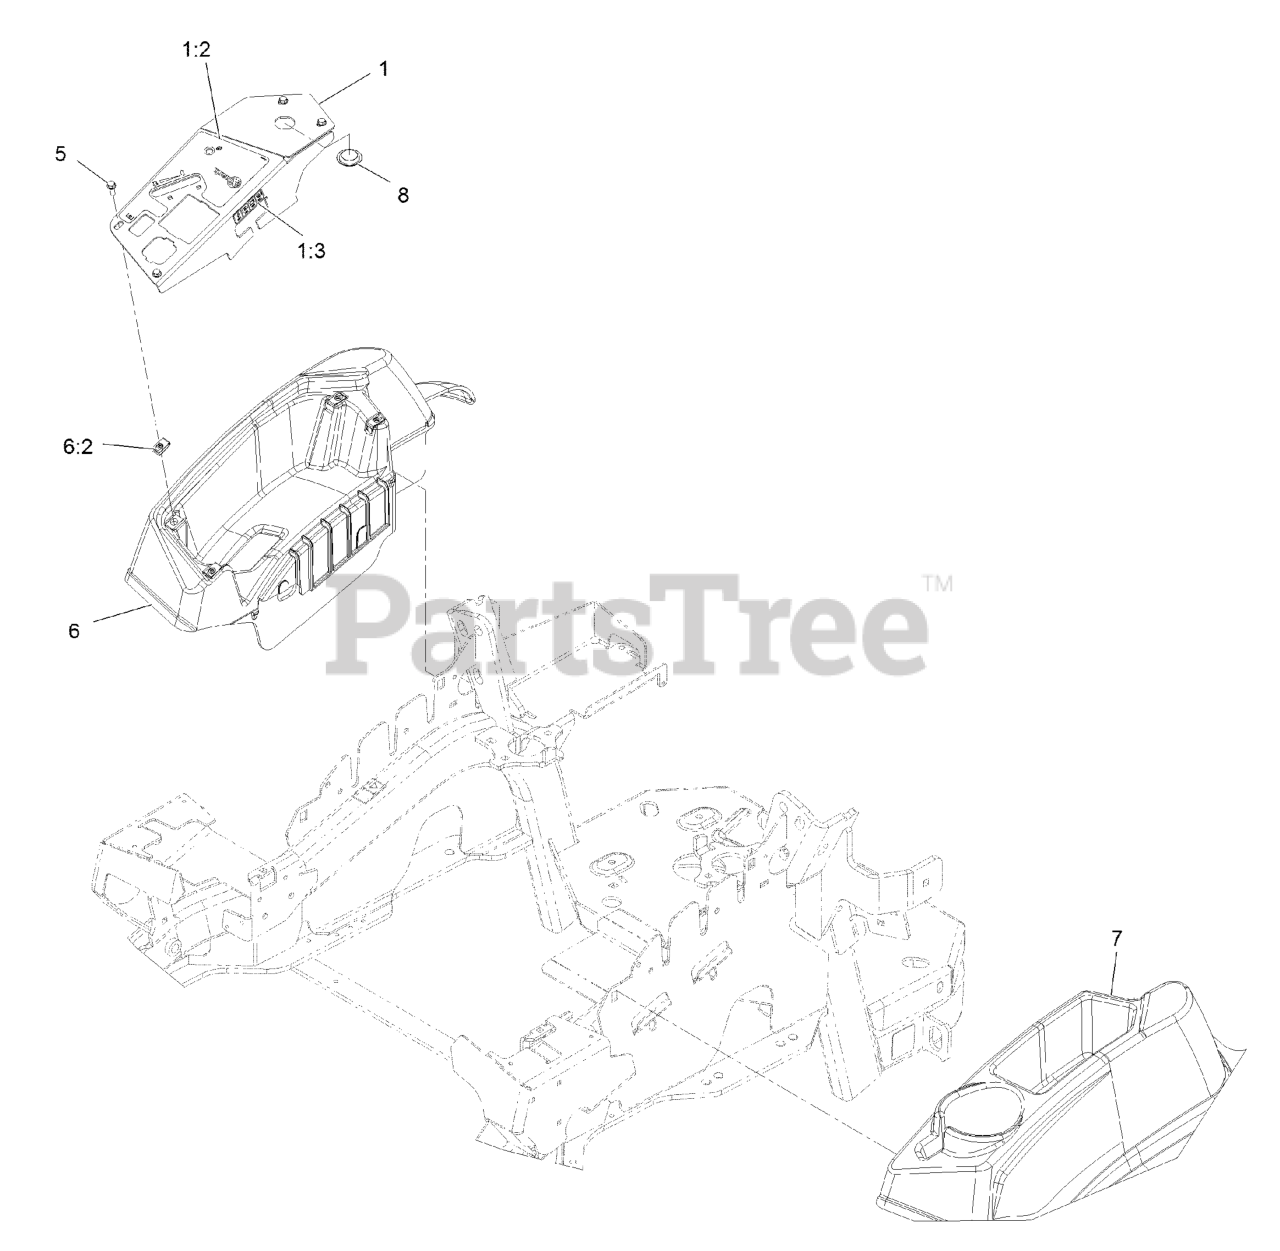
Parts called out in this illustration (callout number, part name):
1	ASM,CONTROL PANEL W/DECAL
1:2	DECAL-CONTROL PANEL EFI
1:3	DECAL-FUSES
2	ASM,THROTTLE CABLE
3	BOLT-CARR
4	NUT-LOCK, NI
5	SCREW-HWH
6	CONSOLE,RH AS ASM
7	CONSOLE, LH AS
8	PLUG-PLASTIC
9	CLAMP-HOSE
